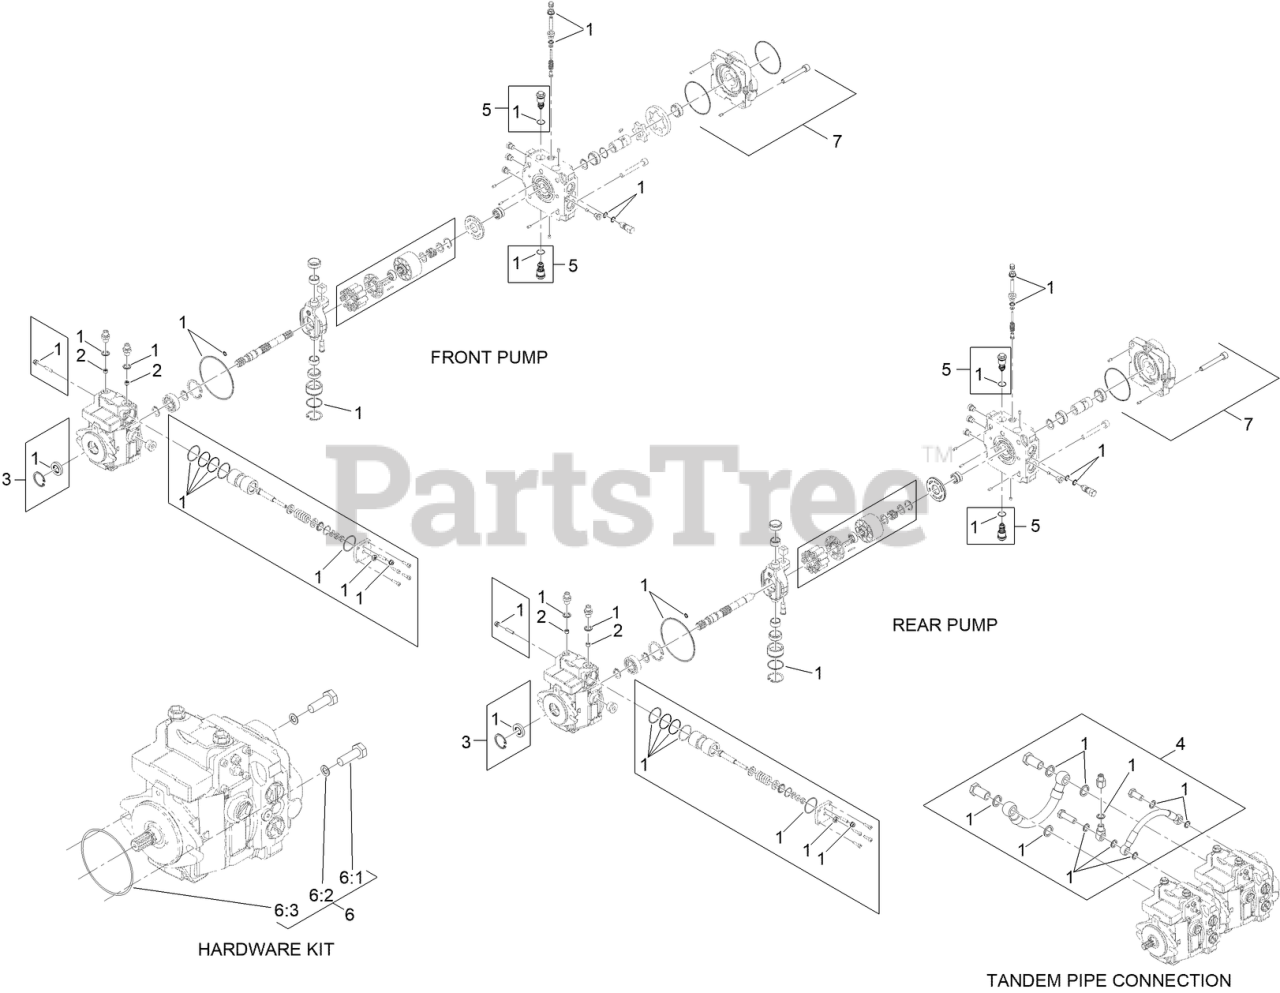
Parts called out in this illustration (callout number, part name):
1	SEAL KIT
2	SPACER-JET
3	SHAFT SEAL KIT
4	TANDEM CONNECTION PIPE KIT
5	VALVE-RELIEF
6	HARDWARE KIT
6:1	BOLT-HEX
6:2	HUB and BEARING ASM
6:3	HUB and BEARING ASM
7	BOLT KIT
